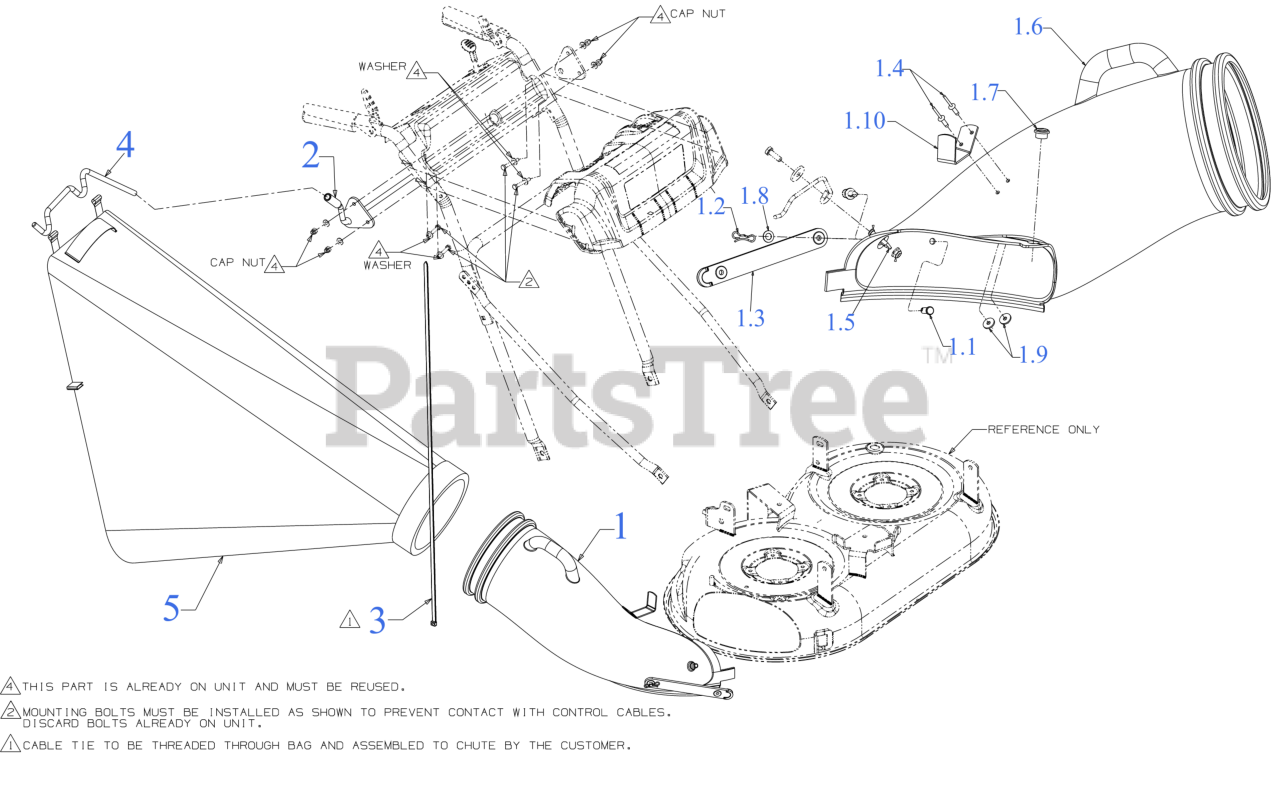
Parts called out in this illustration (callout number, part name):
1	SERVICE REPLACEMENT KITLAC
1.1	CLEVIS PIN 5/16 x 3/4
1.2	BOW TIE COTTER PIN 1/4-5/16
1.3	CHUTE STRAP
1.4	POP RIVET .187 DIA
1.5	PLASTIC RIVET .250
1.6	Not Serviceable/ Order Complete Assembly
1.7	ROD CONTROL BUSHING
1.8	FLAT WASHER
1.8	FLAT WASHER .344 ID x .62 OD x .033
1.9	FLAT WASHER .194x.620x.063
1.10	ELBOW HOLDER BRACKET
2	HOLDER ROD ASSEMBLY (POWDER BLACK)
3	CABLE TIE 36"
4	GRASSBAG HANGER ROD
5	GRASSBAG (2.6 BUSH)
